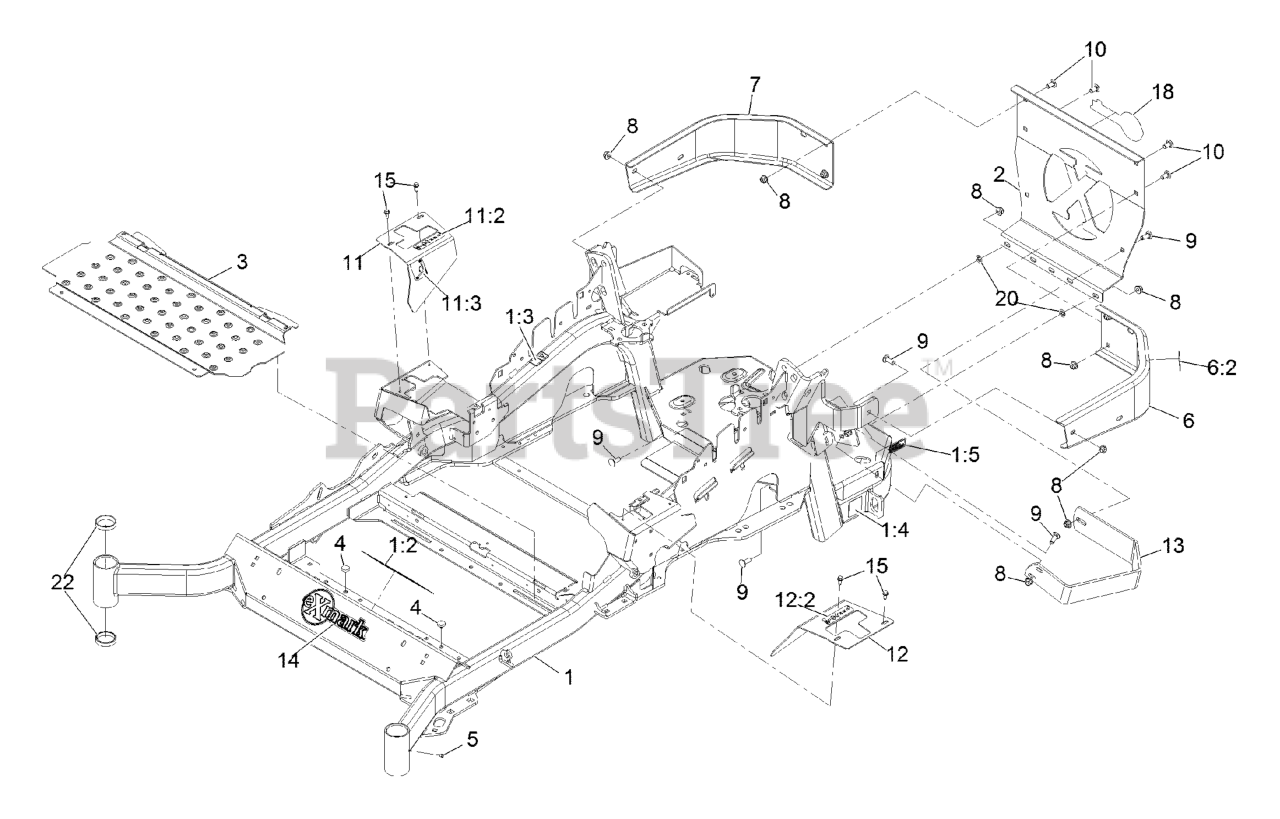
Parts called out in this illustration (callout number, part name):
1	MAINFRAME ASM
1:2	DECAL-DANGER
1:3	DECAL-WARNING
1:4	DECAL-HAZARD, PINCHED FINGER
1:5	DECAL-SPARK ARRESTER
2	PLATE,REAR GUARD
6	LH BUMPER ASM
6:2	DECAL-WARNING
7	BUMPER-RH
8	NUT-HF, NI
9	SCREW-CARR
10	SCREW-CARR
11	RH MOTION CONTROL COVER ASM
11:2	DECAL-CONTROL, MOTION
11:3	DECAL-PARK BRAKE, CE
12	LH MOTION CONTROL COVER ASM
12:2	DECAL-CONTROL, MOTION
13	GUARD-MUFFLER
14	DECAL-EXMARK LOGO
15	SCREW-HWH
18	DECAL-EXMARK LOGO
19	Decal-Patent Ttco.Com
20	NUT-PUSH
21	DECAL-FUEL FILL, CE
22	CUP-BEARING
